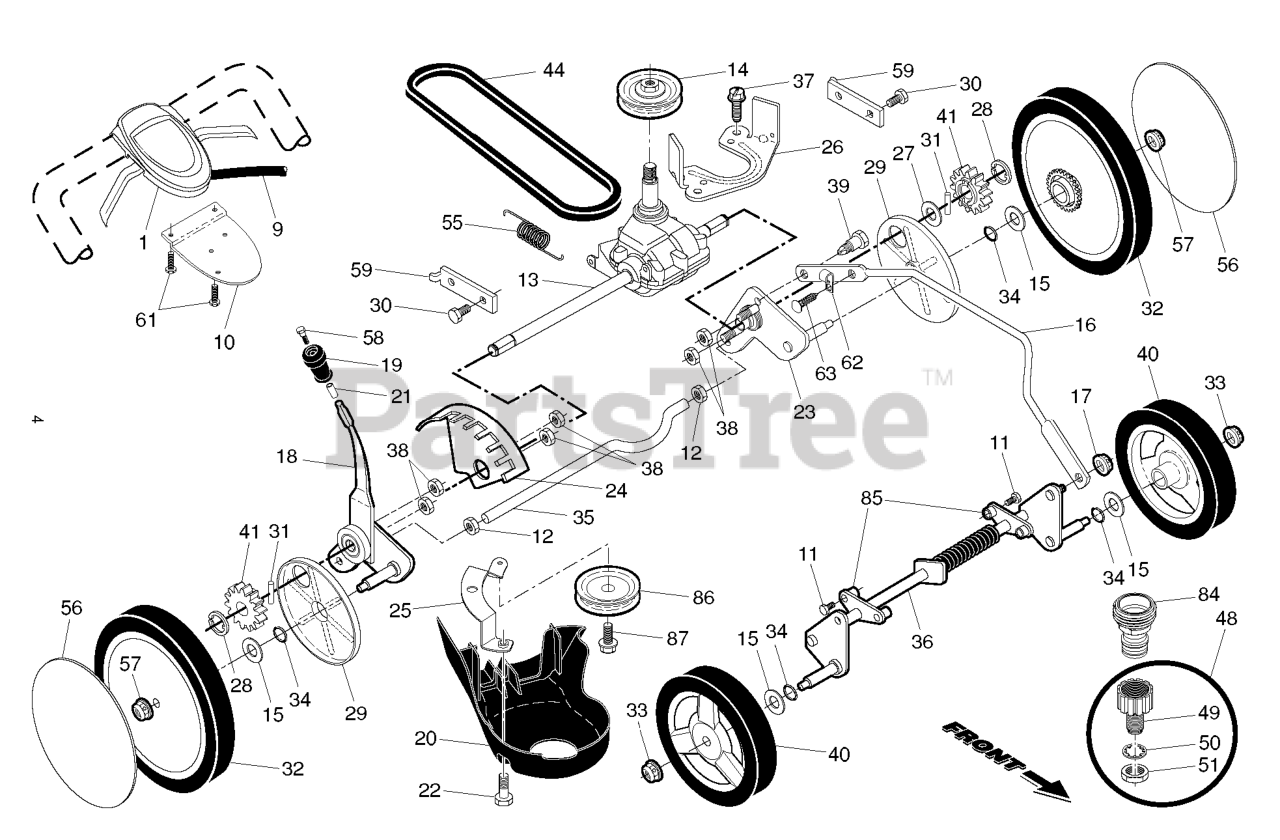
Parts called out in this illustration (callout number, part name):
1	CONTROL.EZ2.22+RG.ST.BLK/BLACK
9	CABLE.DRIVE.RWD.WALK.
9	CABLE.CONTROL.22RGD.GEN2
10	BRACKET.DRIVE.CONTR.GEN2.BLACK
11	SCREW.HX.13X.750
12	NUT.HEX.1/2-20
13	TRANSMISSION.22+AWD.WALK.MOWER
15	WASHER.FLAT.1/2
16	ROD.CONNECTING.RGD.22+.HW.BLAC
17	NUT.LOCK.5/16-18
18	SELECTOR.ASM.22PLUS.SP
19	KNOB.SEL.SPRING.22+.SP.RIB.BLK
20	COVER.REAR.DRIVE.22+2013
21	SCREW.PLASTIC.ANCHOR.5/16
23	ADJUSTER.ARM.ASM.AX.LT.SP.HW
24	BRACKET.WHL.ADJ.9.POS.W/PAD
25	BRACKET.DRIVE.COVER.RGD.
25	BRACKET.DRIVE.COVER.RGD.BZP
26	BRACKET.TRANS.BELT.KEEPER.BZP
27	WASHER
28	E-RING 7/16 RE
29	COVER.DUST.WHEEL.RGD.HW
30	BOLT.5/16HEX.WHS.HD
31	PAWL, DRIVE
32	WHEEL.11.ALPHA.GRY.EXT*
32	WHEEL.11X2.DRIVE.RAD2.BB.GREY
33	NUT.HEX.FLANGE.3/8-16.LO(3 2)
34	O-RING..070X.487.NEOPRENE
35	AXLE.REAR.RGD
36	AXLE.ASM.FRONT.RGD.CLEAR.ZINC
38	NUT.HEX.FLANGE.1/4
39	SHOULDER BOLT SEMI GIMLET PT.
40	WHEEL & TIRES ASSY, FRONT
40	WHEEL.8IN.H3SPK.ALPHA.
41	PINION.12.TEETH.RGD.22+HW
44	BELT.DRIVE.RGD.PLUS
44	RP.BELT.DRIVE.RGD.SS.WALK
48	KIT.WASH-OUT.PORT.ZINC.WALK
49	WASHOUT.PORT.ZINC.RGD.22+
50	WASHER.LOCK.INTERNAL.TOOTH
51	LOCKNUT.HEX.WITH.O-RING
55	SPRING
55	SPRING.RETURN.AUTO.
56	HUBCAP.H.3SPK.GREY
57	NUT.HEX.FLANGE.3/8-16.LOCKNUT
58	SCREW.12-14X1.500
59	BRACKET.SUPPORT.22+RWGD.BZP
61	SCREW, PHILLIPS HEAD 10 X 5/8
62	CLIP.CABLE.BLK
63	FASTENER.PUSH.O.250X0.783
84	COUPLING.QUICK CONNECT
85	BRACKET.FRT.AXLE.SUPPORT
86	RP PULLEY.AWD.IDLER
